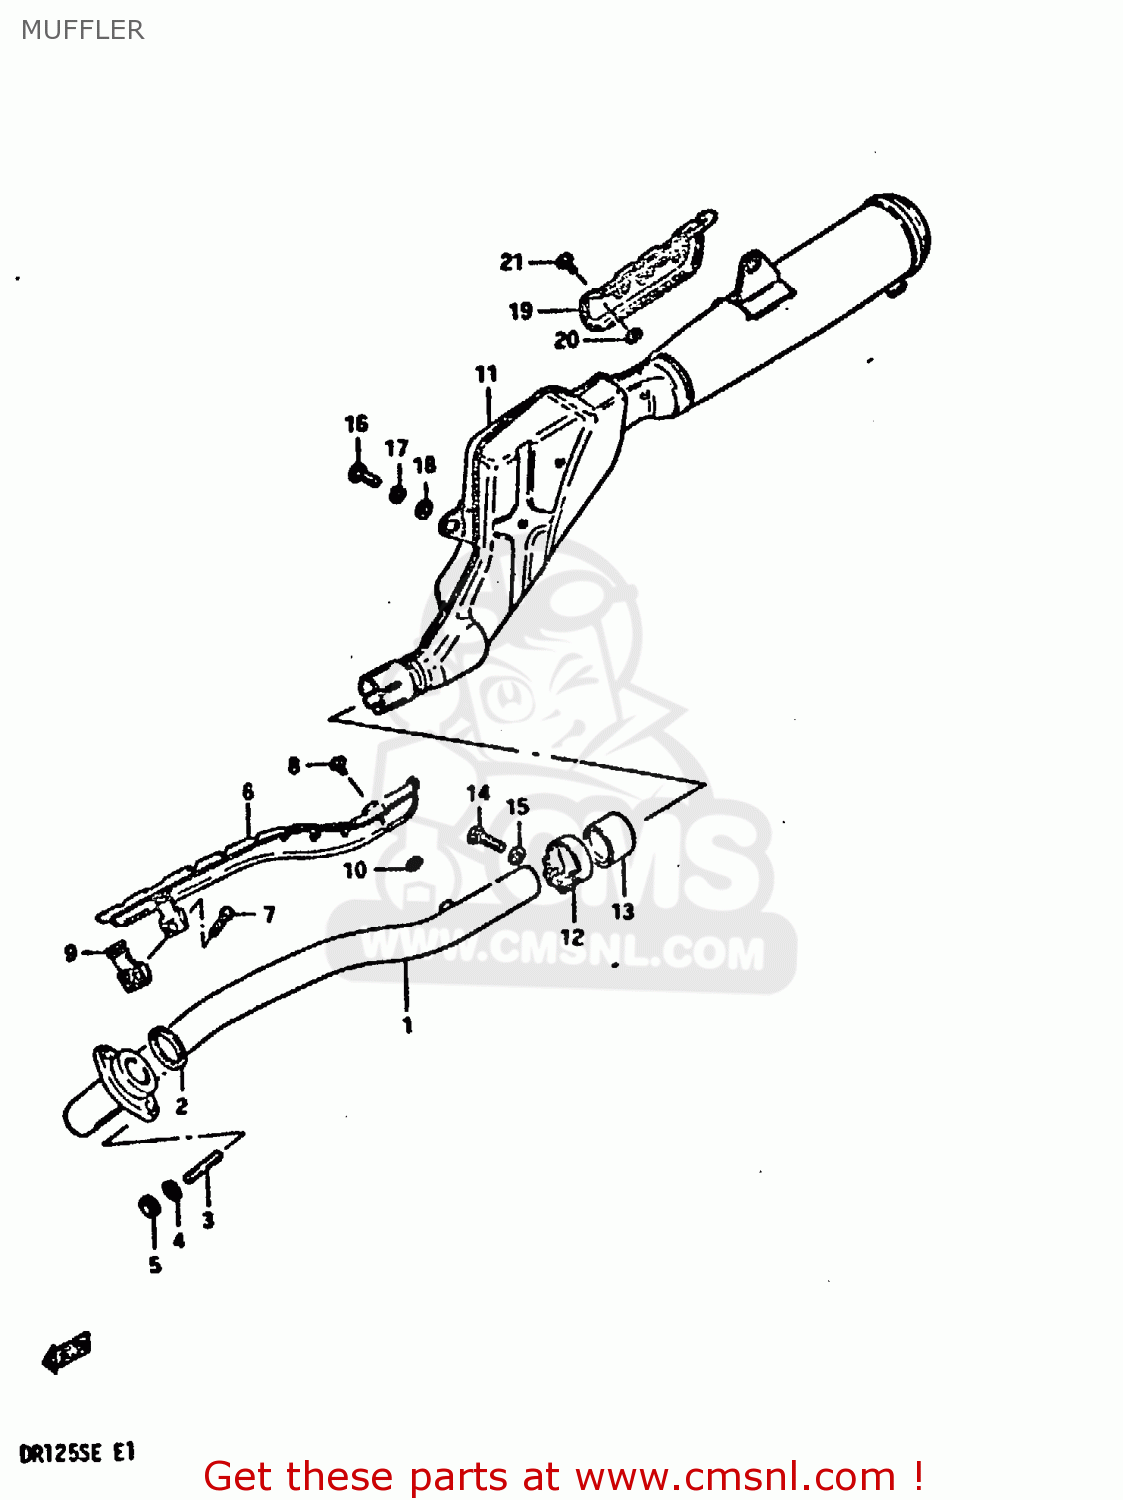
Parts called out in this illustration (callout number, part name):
1	PIPE,EXHAUST
2	GASKET,EXHAUST PIPE (NAS)
3	STUD BOLT L:20
4	LOCK WASHER
5	NUT
6	COVER,EXHAUST PIPE
7	SCREW 5X20
8	SCREW
9	CLAMP,EXHAUST PIPE COVER
10	GASKET 6.2X12X1.5 (MCA)
11	MUFFLER ASSY
12	CLAMP,MUFFLER CONNECTOR
13	CONNECTOR,MUFFLER
14	BOLT 8X35
15	WASHER,8.5X16X
16	BOLT
17	LOCK WASHER
18	WASHER,8.5X16X
19	COVER,MUFFLER
20	GASKET 6.2X12X1.5 (MCA)
21	SCREW
